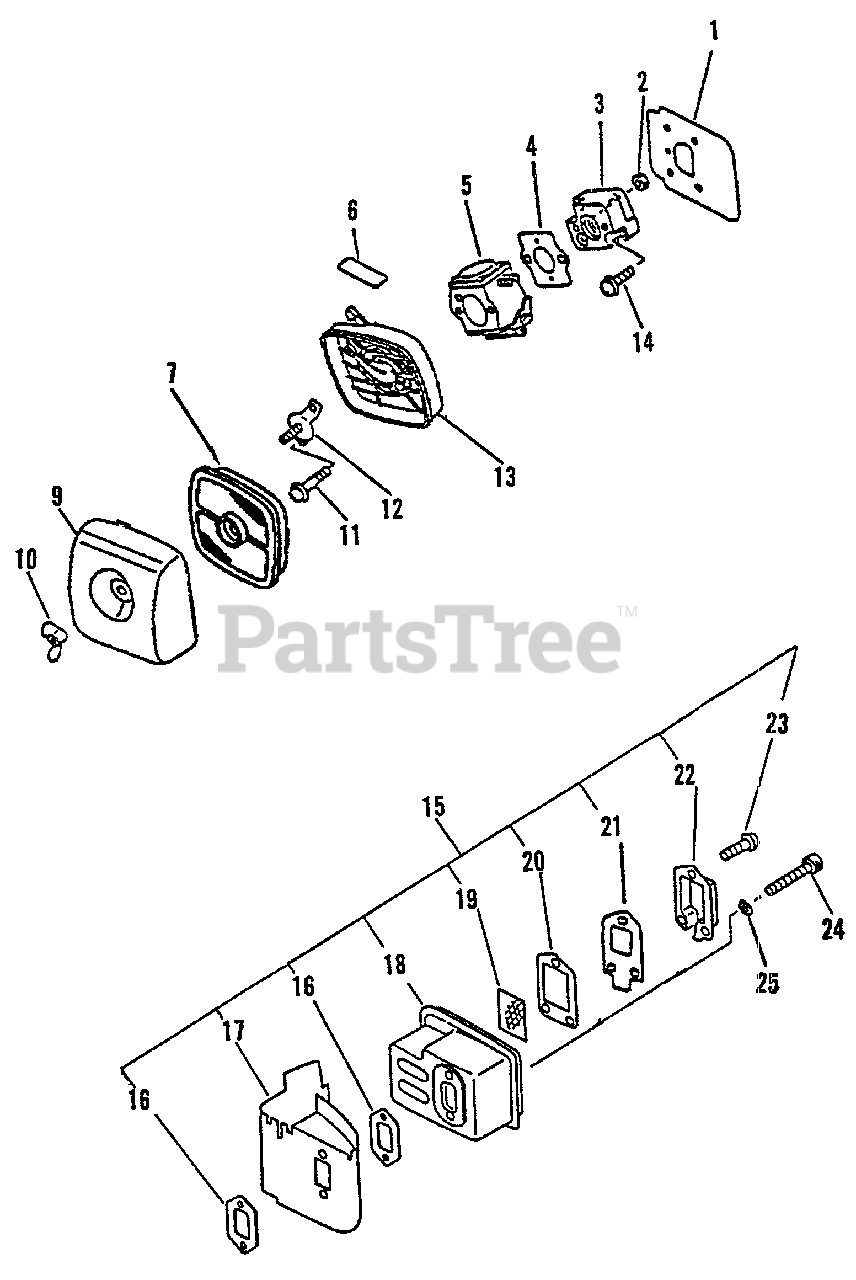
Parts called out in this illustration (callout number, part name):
1	SHIELD, INTAKE
3	INSULATOR, INTAKE
4	GASKET, INTAKE
5	CARBURETOR C1U-K31A
6	LABEL - CHOKE
7	FILTER, AIR - SINGLE LAYER
9	COVER, AIR FILTER - BLACK
10	WINGNUT - 6
11	SCREW - 5X65
12	PLATE, PREVENT
13	AIR FILTER CASE ASSY
14	SCREW - 5X20
15	MUFFLER ASSY
16	GASKET, EXHAUST
17	COVER, EXHAUST
19	SCREEN, SPARK ARRESTOR
20	GASKET, EXHAUST
21	GASKET, EXHAUST - INNER
22	GUIDE, EXHAUST - OUTER
23	SCREW - 4X10
24	SCREW - 5X55
25	WASHER - 5
